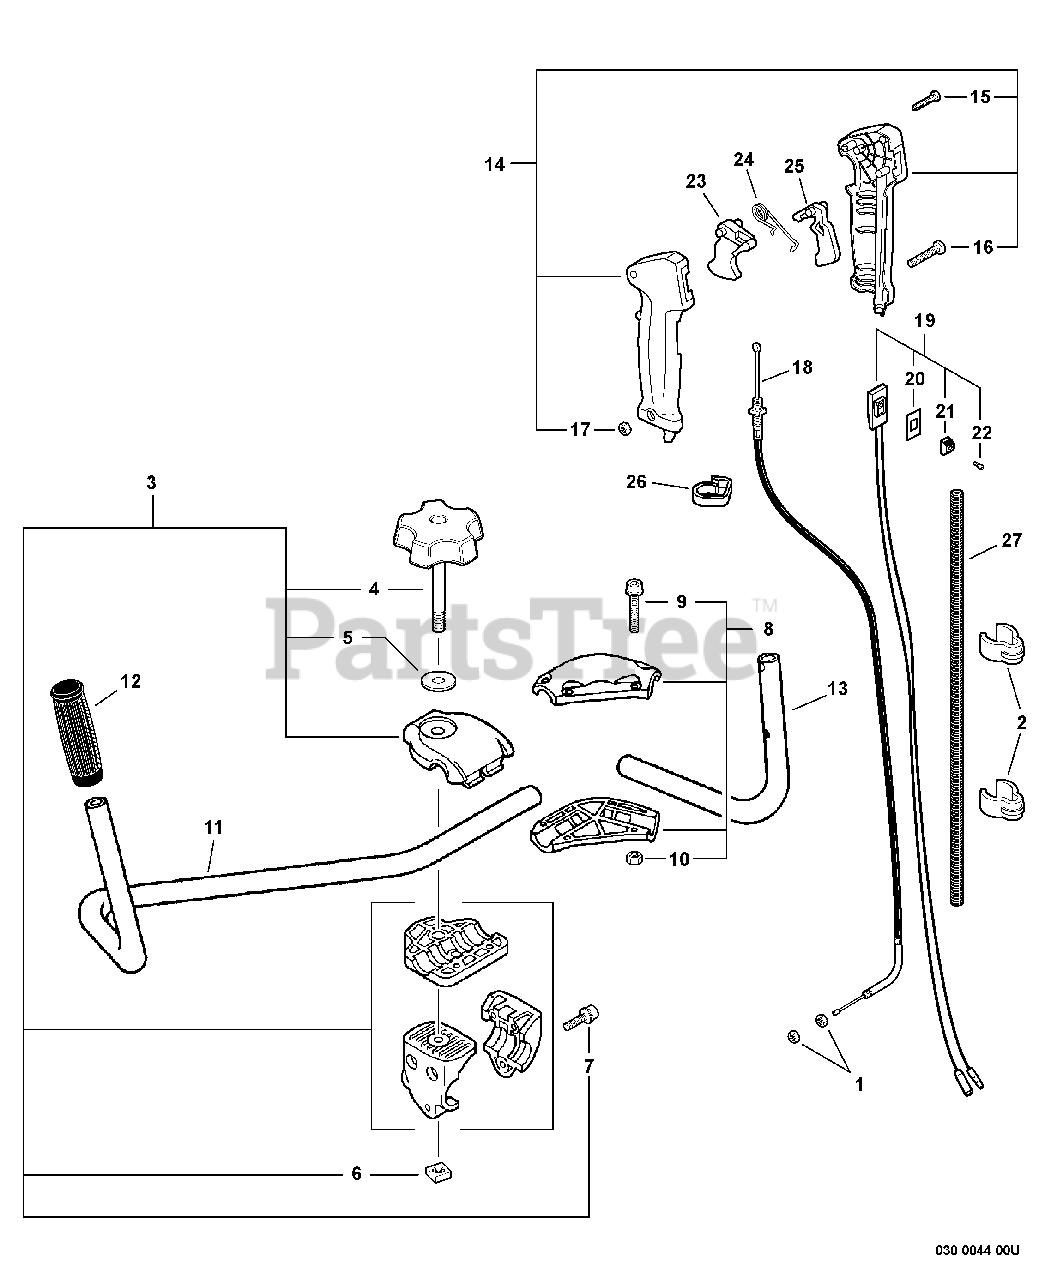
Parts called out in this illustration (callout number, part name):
2	CLIP 28 MM
3	MOUNTING KIT, HANDLEBAR
4	KNOB, SCREW M8
5	WASHER 8
6	NUT 8×1.25
7	BOLT 5×30
8	BRACKET KIT, HANDLEBAR
9	BOLT 5×22
10	NUT M5
11	HANDLEBAR, LEFT
12	GRIP, HANDLE
13	HANDLEBAR, RIGHT
14	CONTROL HANDLE KIT
15	SCREW 3×25
16	SCREW 5×30
17	NUT M5
18	CABLE, THROTTLE
19	SWITCH, ON-OFF
20	LABEL, SWITCH
21	KNOB, SWITCH - ORANGE
22	SCREW 3×10
23	TRIGGER, THROTTLE
24	SPRING, TORSION
25	LOCKOUT, THROTTLE
27	TUBE, FLEXIBLE 7×820
